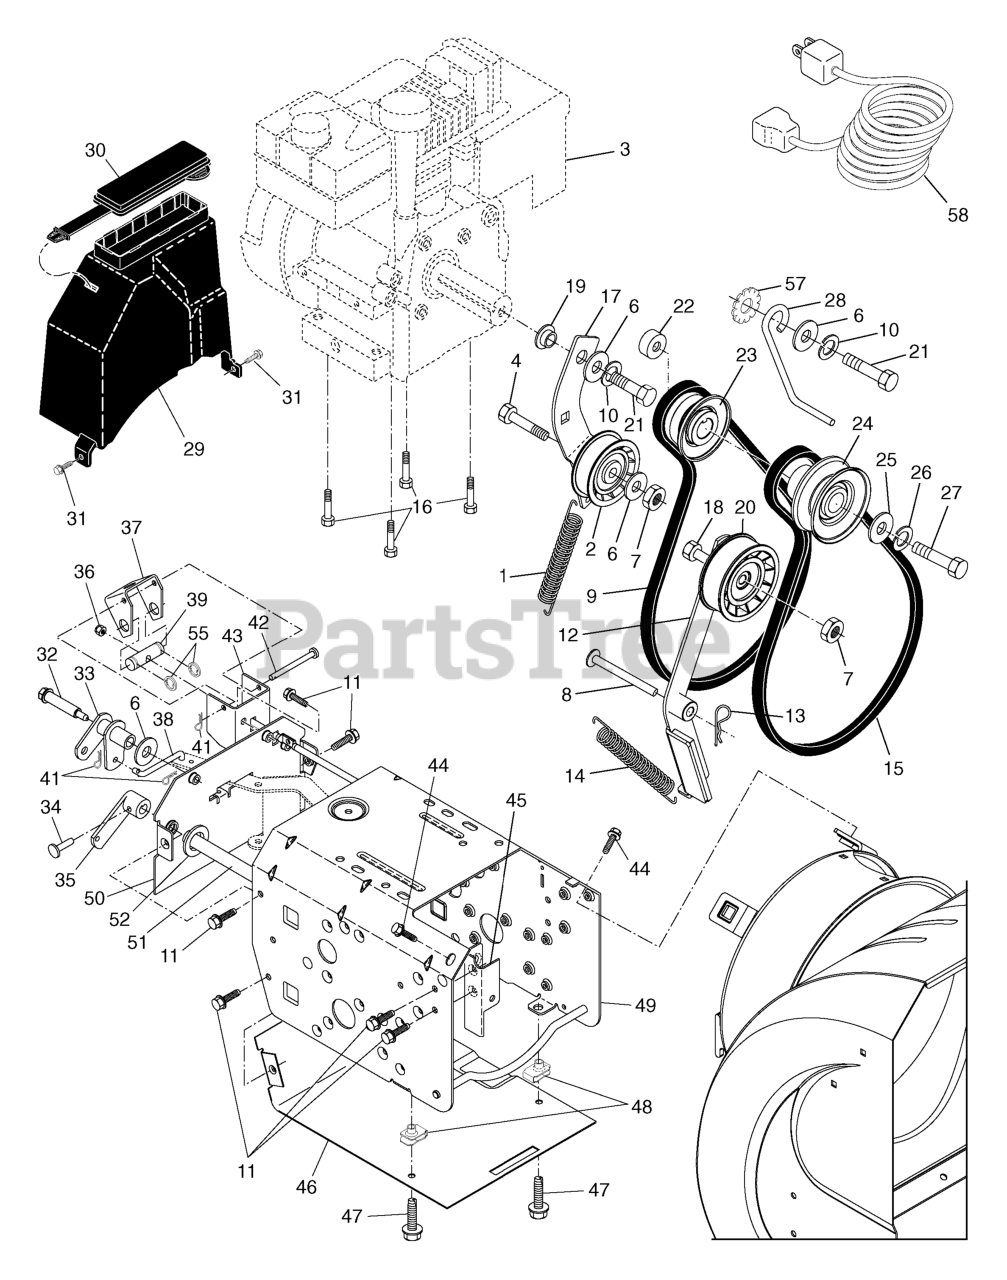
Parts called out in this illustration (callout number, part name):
1	RP SPRING, TRACTION IDLER
2	PULLEY.W/SPACER.2.25
3	Engine, Tecumseh
4	BOLT.5/16-18X1-1/4 FULL.THREAD
6	STEEL WASHER
7	LOCKNUT 5/16-18
8	PIN, IDLER PIVOT
9	V-BELT, TRACTION DRIVE
10	WASHER, LOCK 5/16
11	SCREW, HEX HEAD 5/16-18 X 1/2
12	ARM ASSEMBLY, IMPELLER IDLER
13	RETAINER CLIP PM
14	SPRING, BRAKE
15	V-BELT, IMPELLER DRIVE
16	BOLT 3/8-16X1-1/8
17	IDLER ARM
18	HEX BOLT
19	BUSHING, IDLER PIVOT
20	PULLEY.W/SPACER.2.75
22	SPACER, ENGINE PULLEY
23	PULLEY,ENGINE TRACTION DRIVE
24	PULLEY, ENGINE IMPELLER DRIVE
25	WASHER, FLAT 3/8
26	LOCKWASHER
27	SCREW, HEX HD 3/8-24 X 1-3/8
28	BELT.GUIDE.RH
29	COVER.ASM.BELT/STORAGE
30	COVER.STORAGE.SNOW
31	SCREW, HEX HEAD 1/4-20
32	BOLT, SHOULDER 5/16-18
33	BELLCRANK SHIFTER
34	CLEVIS PIN
35	ARM, AUGER CONTROL
36	NUT.71038.31-18.HEX.NYLOCK
37	BRACKET, PIVOT
38	LINK, SPEED CONTROL
39	TRUNNION, TRACTION
41	RETAINER CLIP
42	PIN, PIVOT BRACKET
44	SCREW 3/8-16X1
45	BRACKET, IDLER PIVOT
46	PAN, FRAME BOTTOM
47	Screw, Hex Head 5/16-18 x 3/4
48	NUT.SPEED.5/16-18
49	FRAME ASSEMBLY
50	PLATE, FRAME END
51	SHAFT, AUGER CONTROL
52	THRUST WASHER
55	RING.CRESENT
57	WASHER EXT TOOTH LOCK 5/16
58	CORD.ELECTRIC.10FT.120V.SNOW
